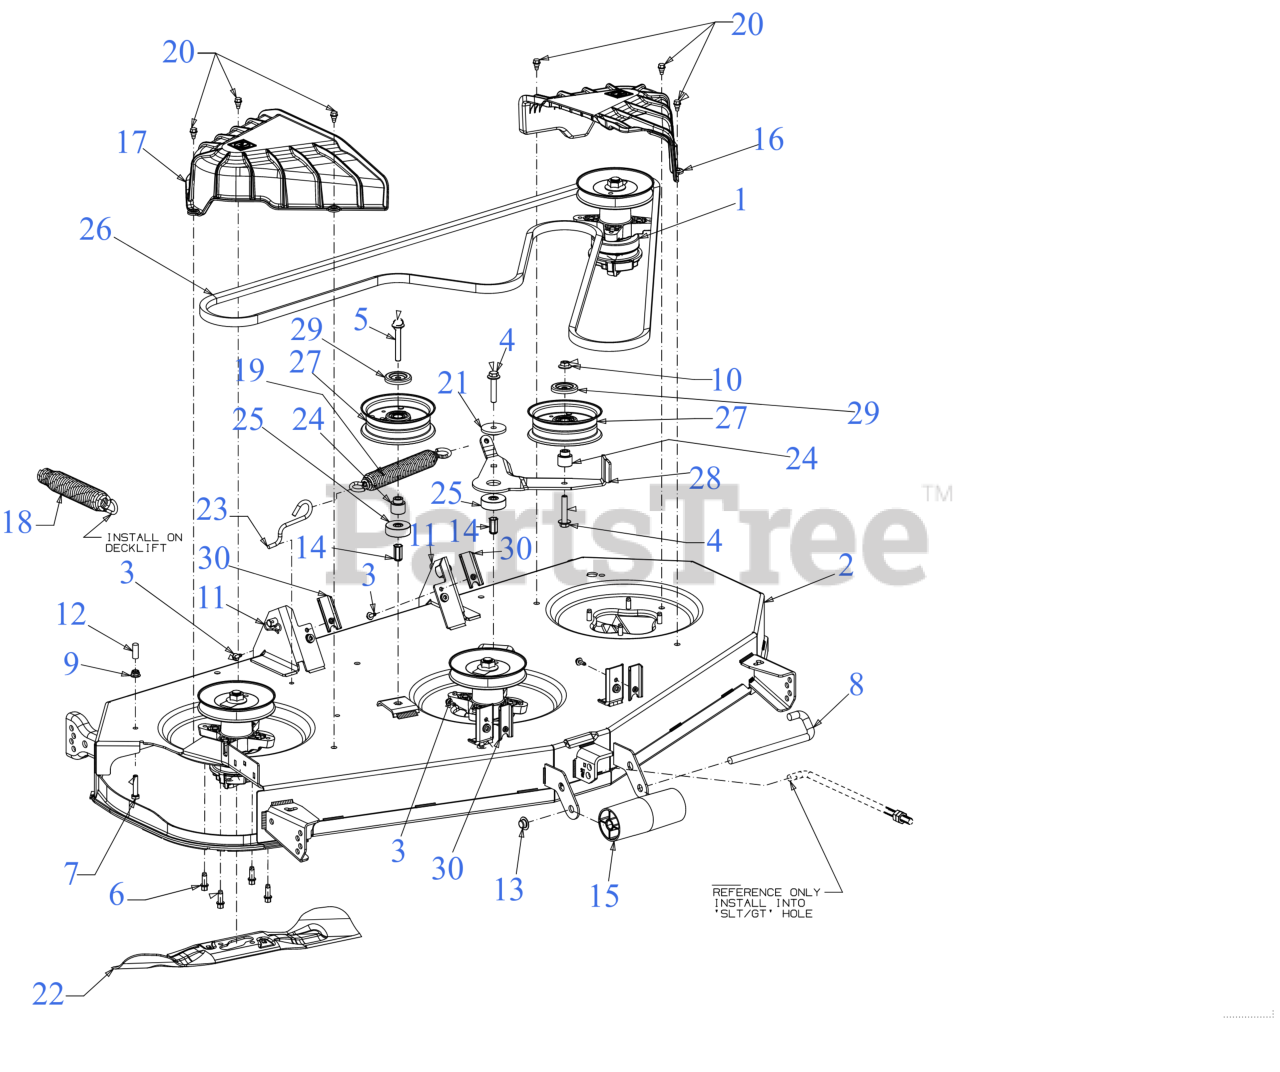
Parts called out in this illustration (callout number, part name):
1	BLADE SPINDLE ASSEMBLY
2	54" FAB FLAT TOP DECK SHELL
3	SCREW M6-1 x .625
4	SCREW 3/8-16 x 2.0
5	SCREW 3/8-16 x 2.75 GR5
6	SCREW 5/16-18 x .875
7	SCREW 5/16-18 x 1.5 LG
8	ROLLER PIN 1/2 x 7.31
9	FLANGE LOCK NUT 5/16-18
10	FLANGE LOCK NUT
11	BOW TIE COTTER PIN
14	NUT RIVET 3/8-16
16	SPINDLE COVER (LH)
17	SPINDLE COVER (RH)
18	LIFT ASSIST SPRING (LARGE)
19	SPRING 1.25" DIA x 8.5" LONG
20	SHOULDER SCREW 1/4-20 x .50
21	SHOULDER SPACER
22	18.611" BLADE (2N1) (FASTATTACH)
22	54" FASTATTACH XTREME MULCH BLADE
22	54" LOW-LIFT SAND FASTATTACH BLADE
23	DECK SPRING HOOK
24	SHOULDER SPACER
25	SPACER .385ID x 1.75OD x .585THK
26	V-BELT B SEC x 139
27	IDLER PULLEY 4.50" DIA
28	IDLER PIVOT BRACKET
29	IDLER PULLEY CAP
